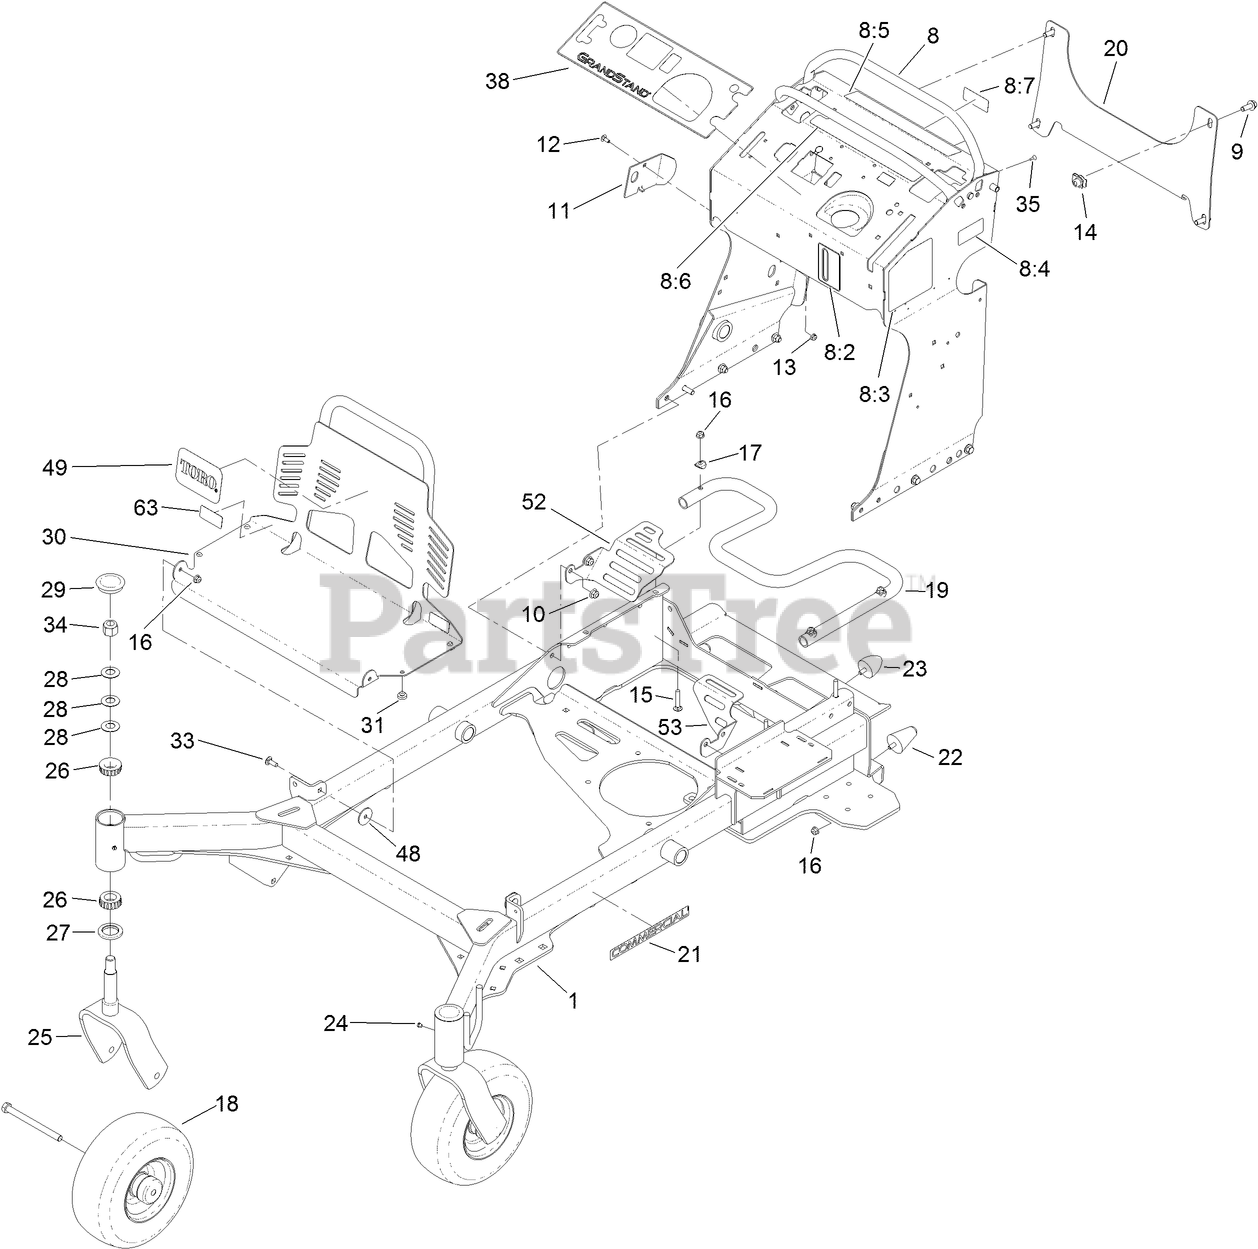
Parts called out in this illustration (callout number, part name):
8	TOWER DECAL ASM
8:2	DECAL-LEVEL, OIL
8:3	DECAL-SERVICE AID
8:4	DECAL-FILL, FUEL
8:5	OBS DECAL-CAUTION
8:6	DECAL-CONTROLS
8:7	DECAL-FUSE
9	SCREW-HHF
10	NUT-HF, NI
11	PLATE-STRIKER
12	SCREW-CARR
13	NUT-HF
14	Nut-Tinnerman
15	SCREW-CARR
16	NUT-HF, NI
17	WASHER
18	WHEEL/TIRE AND BEARING ASM
19	TUBE-MOUNT, FUEL TANK
20	BRACKET-CROSS
21	DECAL-COMMERCIAL
22	BUMPER-RUBBER
23	BUMPER-RUBBER
24	FORK-CASTER
26	BEARING-ROLLER, TAPERED
27	SEAL-GREASE
28	WASHER-BELLVILLE
29	CAP-GREASE
30	GUARD-ENGINE
31	BUMPER
33	BOLT-CARR
34	NUT-LOCK, NI
35	RIVET-POP
38	DECAL-PANEL, CONTROL
48	WASHER-NYLON
52	GUARD-FAN, RH
53	GUARD-FAN, LH
63	DECAL-WARNING, NO RIDERS
